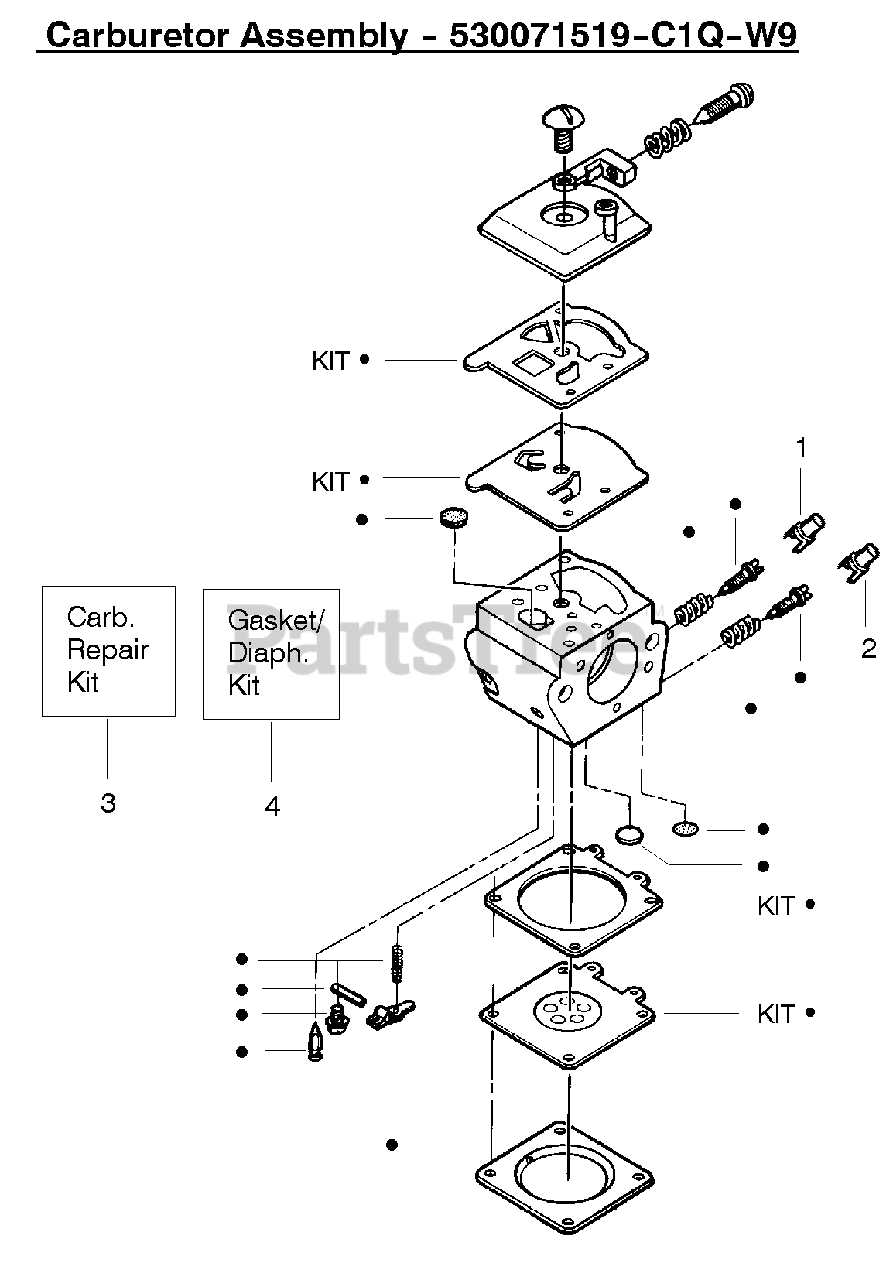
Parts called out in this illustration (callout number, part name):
1	Limiter Cap-High
2	Limiter Cap-Low
3	Carburetor Repair Kit
4	Gasket/Diaphragm Kit (KIT=Indicates Contents)
